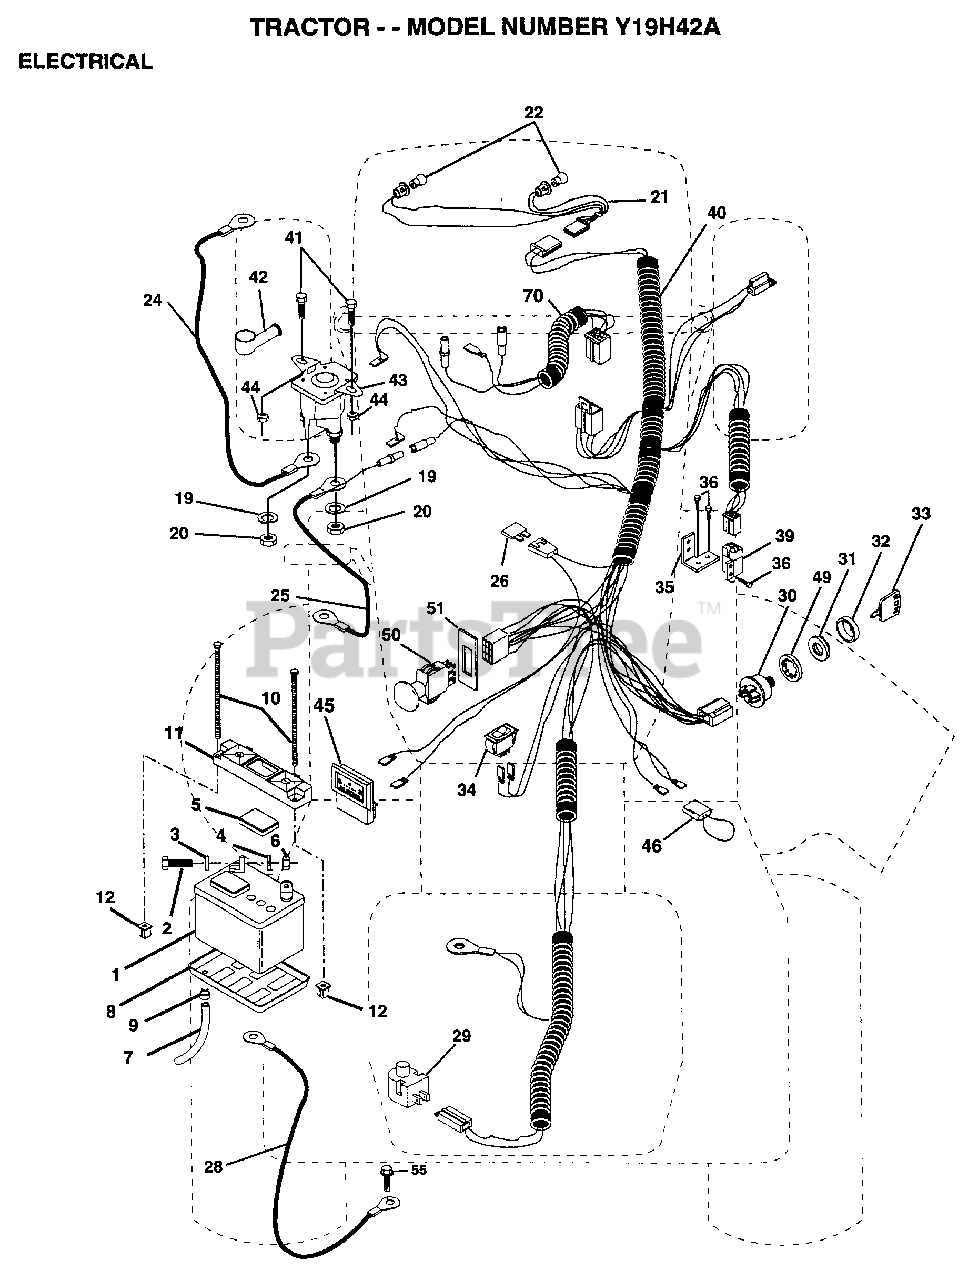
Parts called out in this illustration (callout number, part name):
2	BOLT LT
3	WASHER
4	LOCKWASHER
8	TRAY T, BATTERY
9	HOSE CLAMP T
20	NUT
21	"HARNESS,LIGHT SOC"
22	HEADLAMP BULB
24	CABLE T, BATTERY
25	CABLE.6GA.22W/16W
26	FUSE HYT
28	CABLE.GRND.6GA.21
29	SWITCH SEAT *SUBS/2*
32	COVER KEY SWITCH
33	KEY MLD GEN DELTA
34	SWITCH LT
35	BRACKET LT
36	SCREW
39	SWITCH INTERLOCKT (2 2)
40	HARNESS.ING.ELEC.
41	BOLT.HX.1/4-20
44	NUT
45	AMMETER
46	PROTECTION LOOP
49	LOCKWASHER
51	RING RETAIN PTO
55	SCREW LT
70	HARNESS ENG B&S
